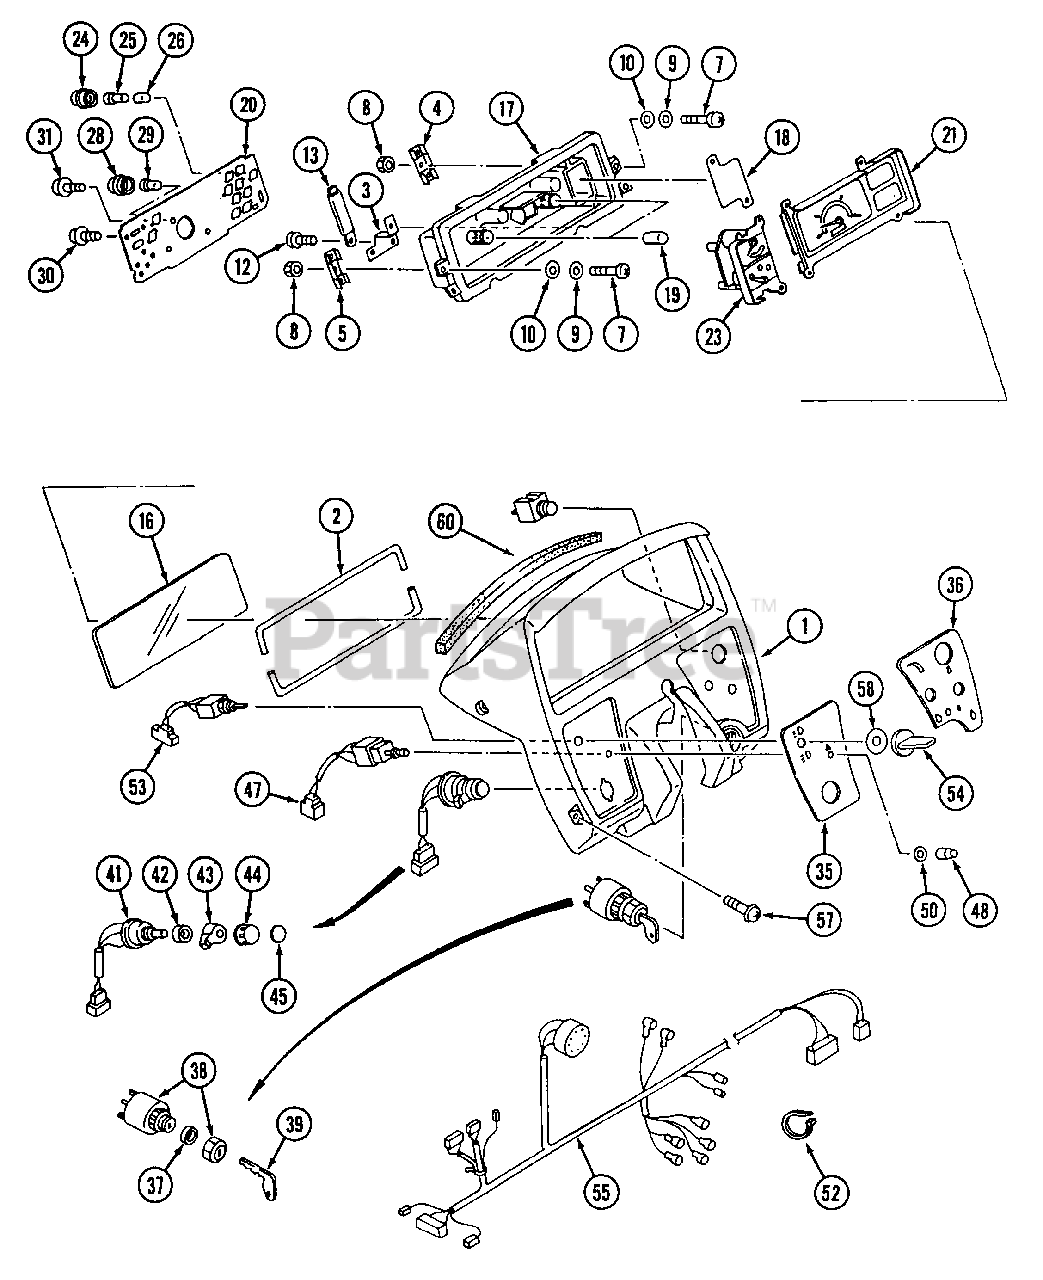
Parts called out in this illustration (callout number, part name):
16	Glass Ass'y.
18	Plate, Monitor
19	Lens, Indicator
23	Meter, Fuel & Temp.
35	Label, Panel L.H.
36	Label, Panel R.H.
37	Packing, Starter
38	Switch, Starter
39	Key, Starter
41	Switch, Body Ass'y.
42	Ring, Nut
43	Flasher, Lever
44	Lighting, Knob
48	Switch, Cover
53	Switch, Light H/L
58	Packing, Rubber
